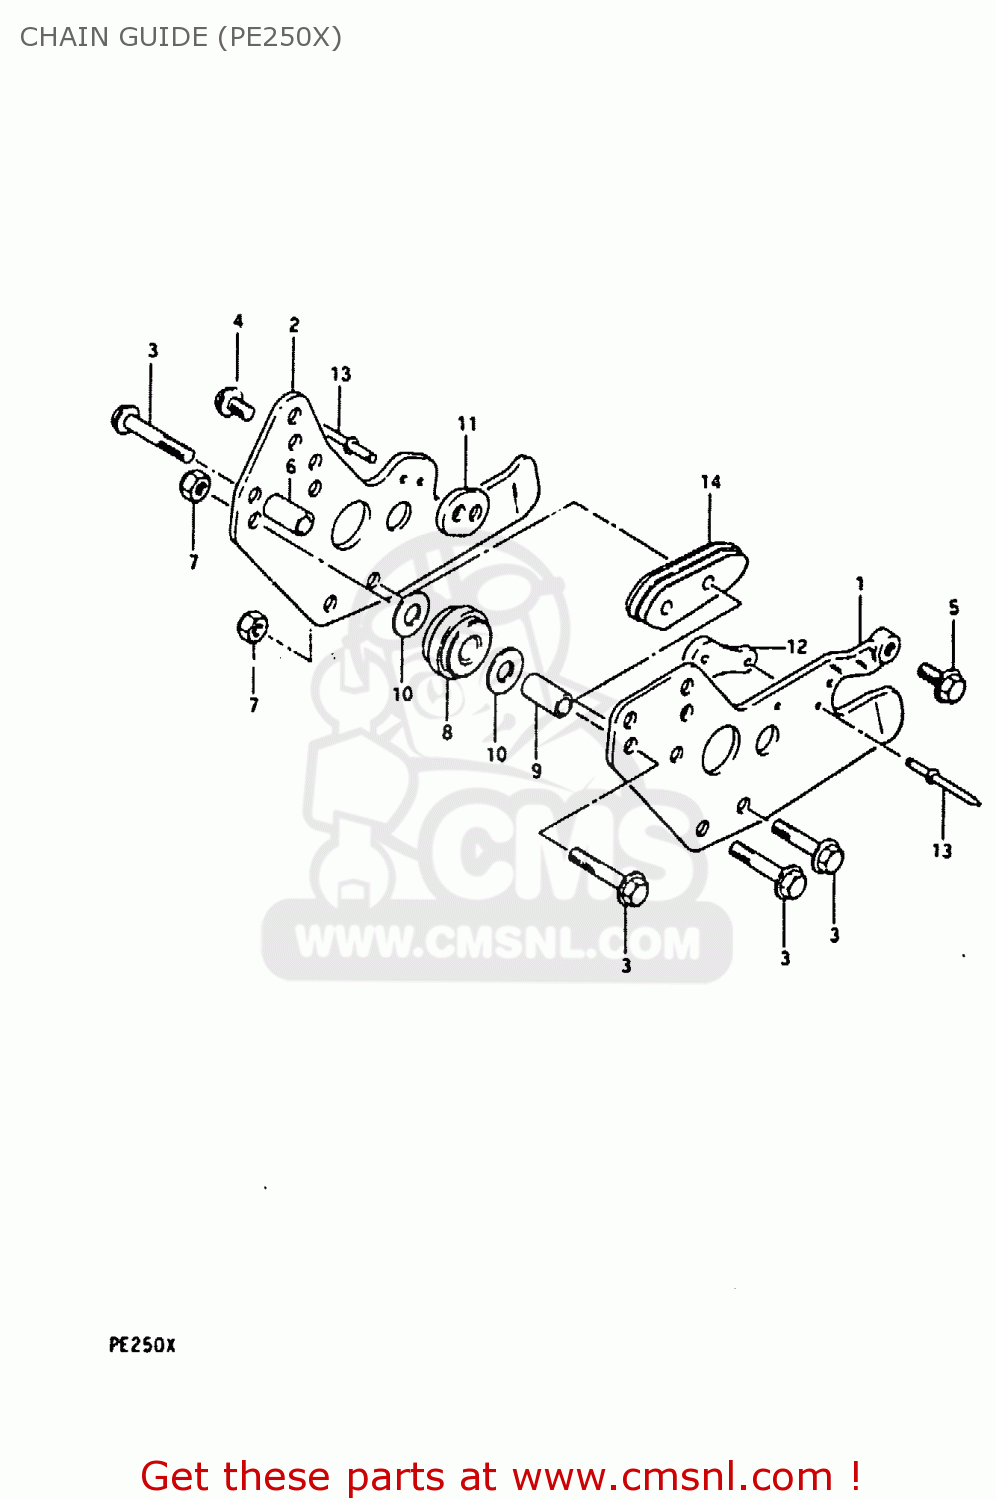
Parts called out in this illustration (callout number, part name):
1	PLATE,CHAIN GUIDE,OUTER
2	PLATE,GUIDE CHAIN
3	BOLT
4	BOLT
5	BOLT
6	SPACER(6.8X10X24.2)
7	NUT
8	ROLLER,CHAIN GUIDE
9	SPACER,CHAIN GUIDE ROLLER
10	WASHER
11	PAD,DRIVE CHAIN GUIDE
12	PAD,DRIVE CHAIN GUIDE
13	RIVET
14	DEFENSE,CHAIN GUIDE
